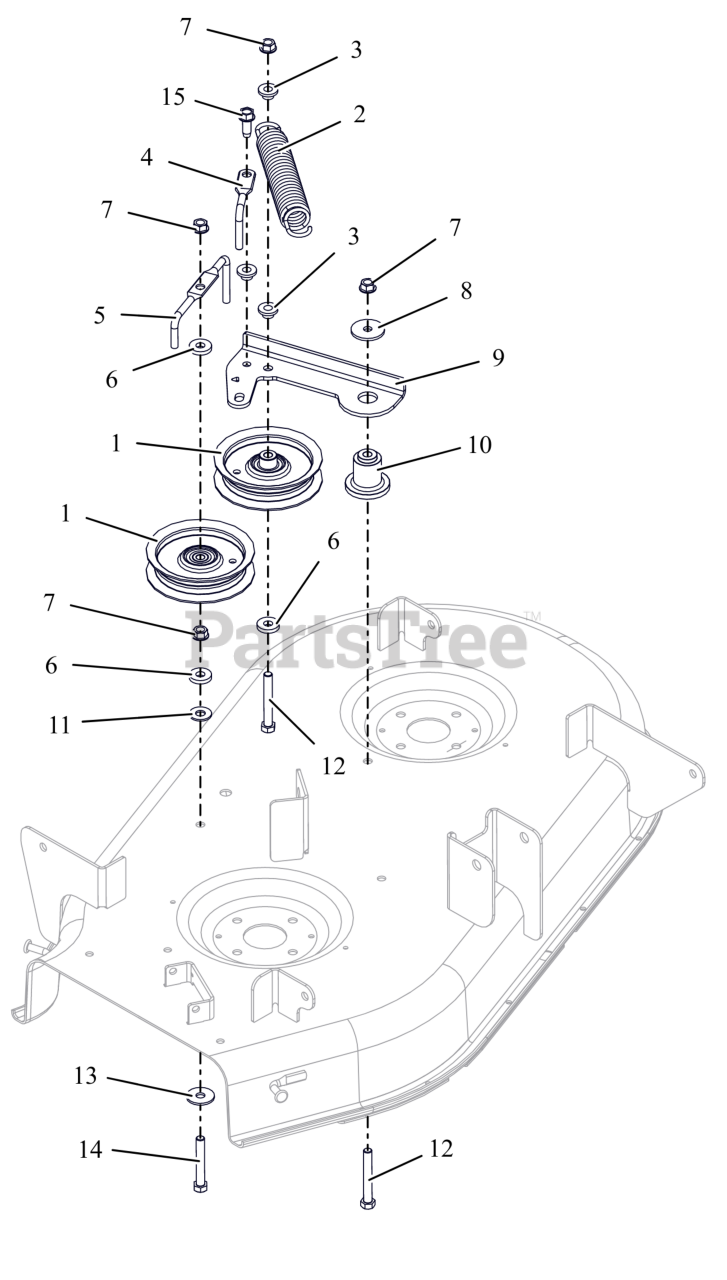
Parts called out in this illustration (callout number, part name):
1	IDLER, FLAT - 4.06" X .75"
2	SPRG, EXTENSION
3	BSHG-FLG .385X.500X.875X.406
4	WIREFORM-BELT FINGER
5	BELT FINGER
6	WSHR, FLT .406X1.00X.188 ZCC
7	NUT-LK-CTR-FLG .375-16 GF ZCC
8	WSHR, FLT .380X1.50X.125 ZCC
9	ARM- IDLER -34 EDGE
10	BSHG- FLANGED
11	WSHR,FLT .438X1.00X.083 ZCC
12	BLT, HEX .38-16X2.75 G5 ZCC
13	WSHR FL STL .406X1.25X.10ZC120
14	BLT, HEX .38-16X2.50 G5 ZCC
15	SCR-TAP .38-16X1.00 HWH TR ZCC
